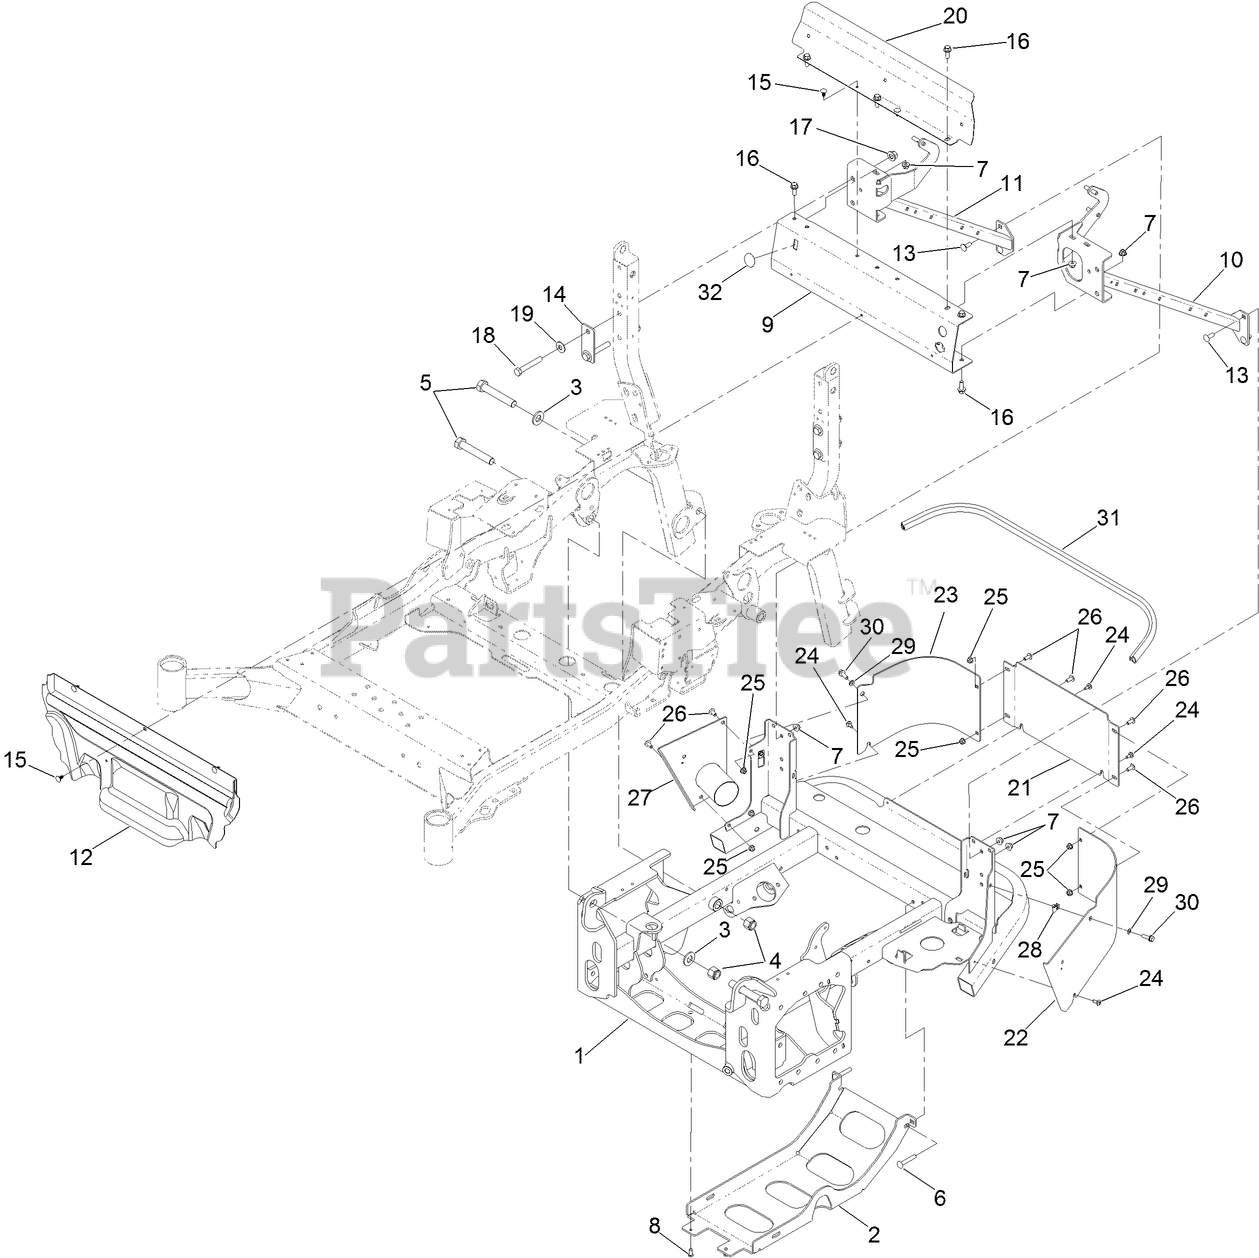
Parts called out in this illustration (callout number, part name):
1	FRAME-POWER
2	PLATE-SKID
3	WASHER
4	NUT-LOCK, NI
5	SCREW-HH
6	BOLT-CARR, SHORT NECK
7	NUT-HF, NI
8	SCREW-BHTF
9	CHANNEL-CROSS
10	BRACE-ROPS, LH
11	BRACE-ROPS, RH
12	PANEL-DEFLECTOR, HEAT
13	SCREW-CARR
14	PLATE-SPACER
15	PLUG-PLASTIC
16	SCREW-HHF
17	NUT-LOCK
18	SCREW-HH
19	WASHER-SPRING
20	SHIELD-AIR
21	PLATE-BUMPER, CENTER
22	PLATE-BUMPER, LH
23	PLATE-BUMPER, RH
24	SCREW-SHOULDER
25	NUT-HF, NI
26	SCREW-TORX
27	PLATE-EXHAUST
29	WASHER-BELLEVILLE
30	SCREW-HHF
31	SEAL-BULB
32	DECAL-COVER
